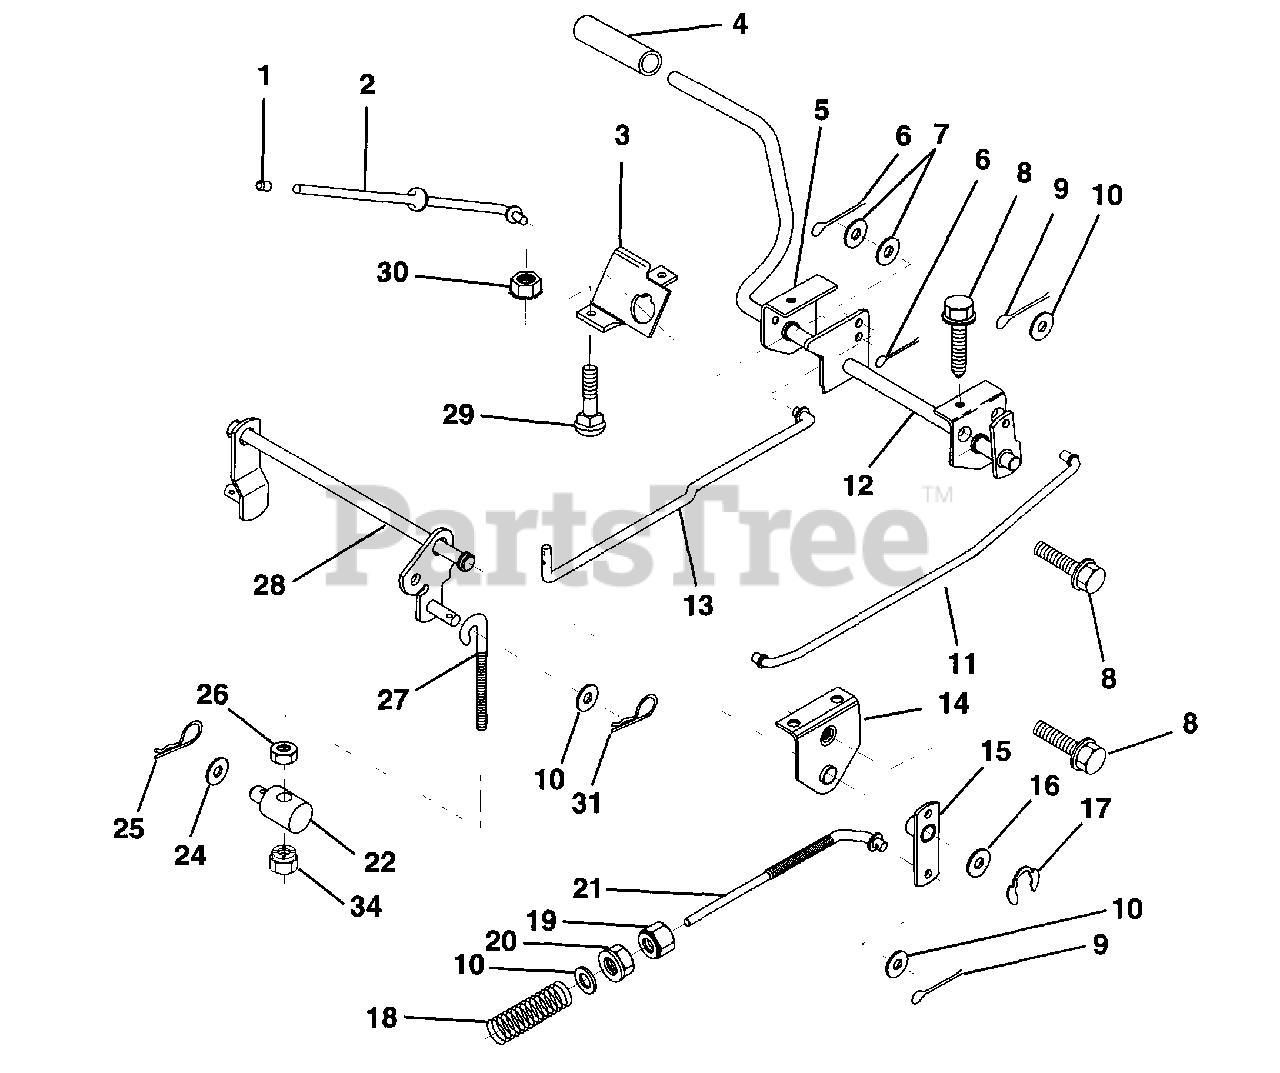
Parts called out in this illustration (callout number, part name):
1	Cap, Plunger
2	Rod, Parking Brake
3	Bracket, Parking Brake
4	Cover, Pedal
5	Bracket, Clutch/Brake Pedal, L.H.
6	Pin, Cotter 3/32 x 3/4
7	Washer 13/32 x 5/8 x 16 Ga.
8	Screw, Hex, Thd. Roll. 5/16-18 x 1/2
9	Pin, Cotter 1/8 x 3/4
10	Washer 13/32 x 13/16 x 16 Ga.
11	Rod, Brake Front
12	Assembly, Clutch/Brake Pedal
13	Rod, Clutch
14	Bracket, Lift, Shaft
15	Assembly, Brake, Pivot, Arm
16	Washer 25/32 x 1-1/8 x 16 Ga.
17	Ring, Clip
18	Spring, Brake Rod
19	Nut, Hex, Jam 3/8-16 UNC
20	Nut, Lock, hex. w/Ins. 3/8-16 INC
21	Rod, Rear Brake
22	Trunnion, Lift
24	Washer 13/32 x 1-1/4 x 12 Ga.
25	Spring, Retainer
26	Nut, Centerlock 3/8-16 UNC
27	Link, Threaded
28	Assembly, Rear Mower Lift
29	Bolt, Carriage 5/16-18 UNC x 3/4
30	Nut, Keps 5/16-16 UNC
31	Retainer Spring
34	Nut, Crownlock 3/8-16 UNC
